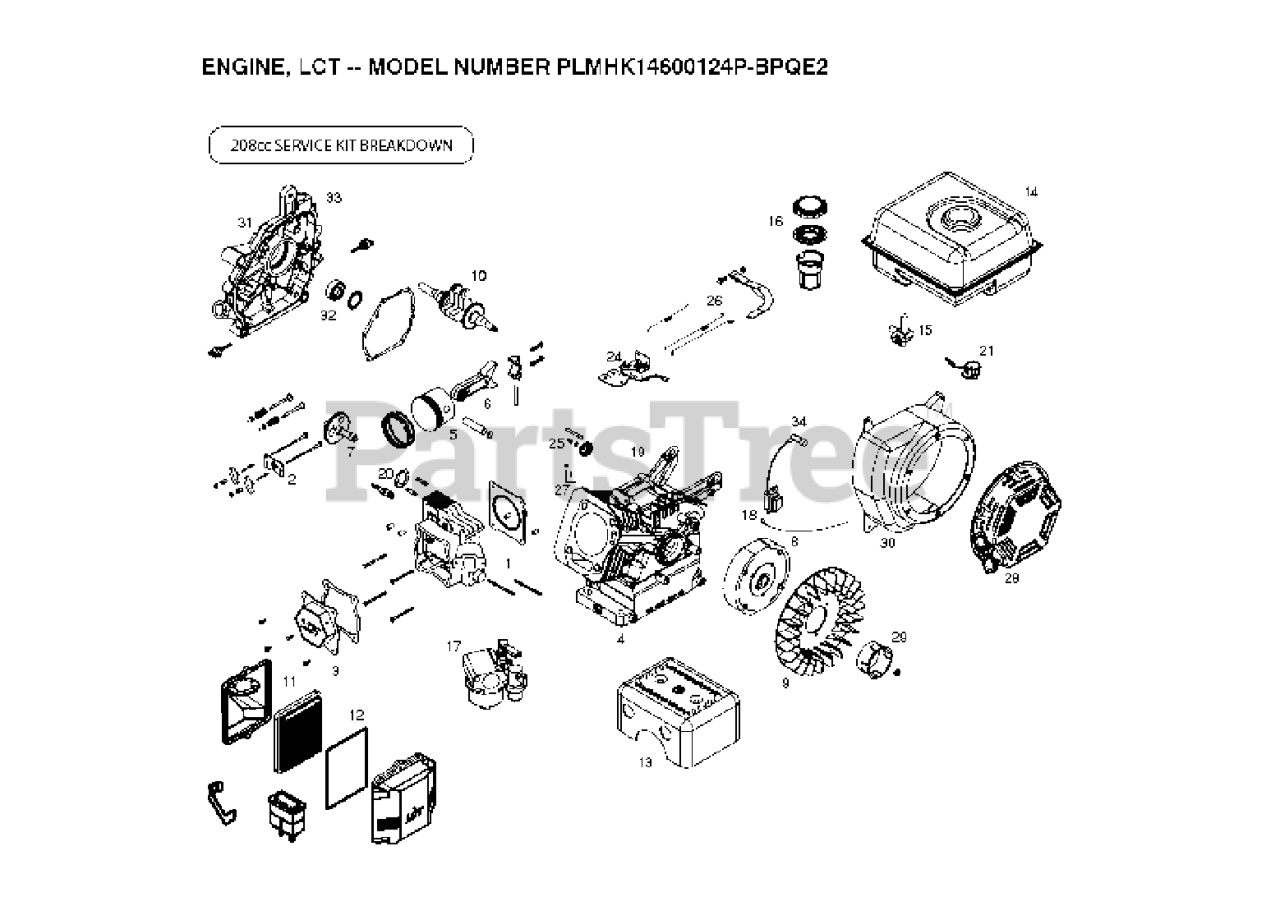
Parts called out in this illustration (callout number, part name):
1	CYLINDR.HEAD.SRV.KIT W/GASKET
2	KIT.PUSH.ROD.SRV(SK208-1001)
4	KIT.CYLINDER.SRV(SK208-1300)
5	KIT.PISTON.SRV(SK208-1400)
6	KIT.CONNECT.ROD.SRV(SK208-1500
7	KIT.CAMSHAFT.208CC.LCT
8	RP KIT.FLYWHEEL.SERVICE
9	FLYWHEEL FAN 420586
10	RP KIT.CRANKSHAFT.SRV
11	KIT.AIRFLTR.ASY.SRV(SK208-2002
12	KIT.SERV.PAP.FILTER(SK208-2012
13	KIT.49STATE.MUFFLER(SK208-2101
14	KIT.49STATE.FUEL.TK(SK208-2200
15	FUEL.PETCOCK.LQA.3/16".LCT
16	KIT.49STATE.FUEL.TK(SK208-2300
17	KIT.CARBURETOR.SERV(SK20-2401)
18	KIT.IGNITION.COIL
19	KIT.IGNITION.(CDI BOX)
20	KIT.SPARK.PLUG.SRV(SK1500)
21	KIT.ENGINE.ON/OFF.LCT.208CC
24	KIT.THROTTLE.CONTRL(SK206-2800
25	KIT.GOVERNOR.GEAR(SK208-2900)
26	RP_IT.GOVERNOR.ARM(SUMMER ENG)
27	KIT.GOVERNOR.CRANK(SK208-3100)
28	KIT.RECOIL.STARTER(HEX) BLACK
29	KIT.STARTER.CUP.SRV(SK208-3300
30	KIT.BLOWER.HSG.SRV(SK208-3400)
31	CRANKCASE COVER ASSY
32	KIT.SEAL.SERVICE(SK208-3900)
34	RP KIT.SPARK.PLUG.BOOT
